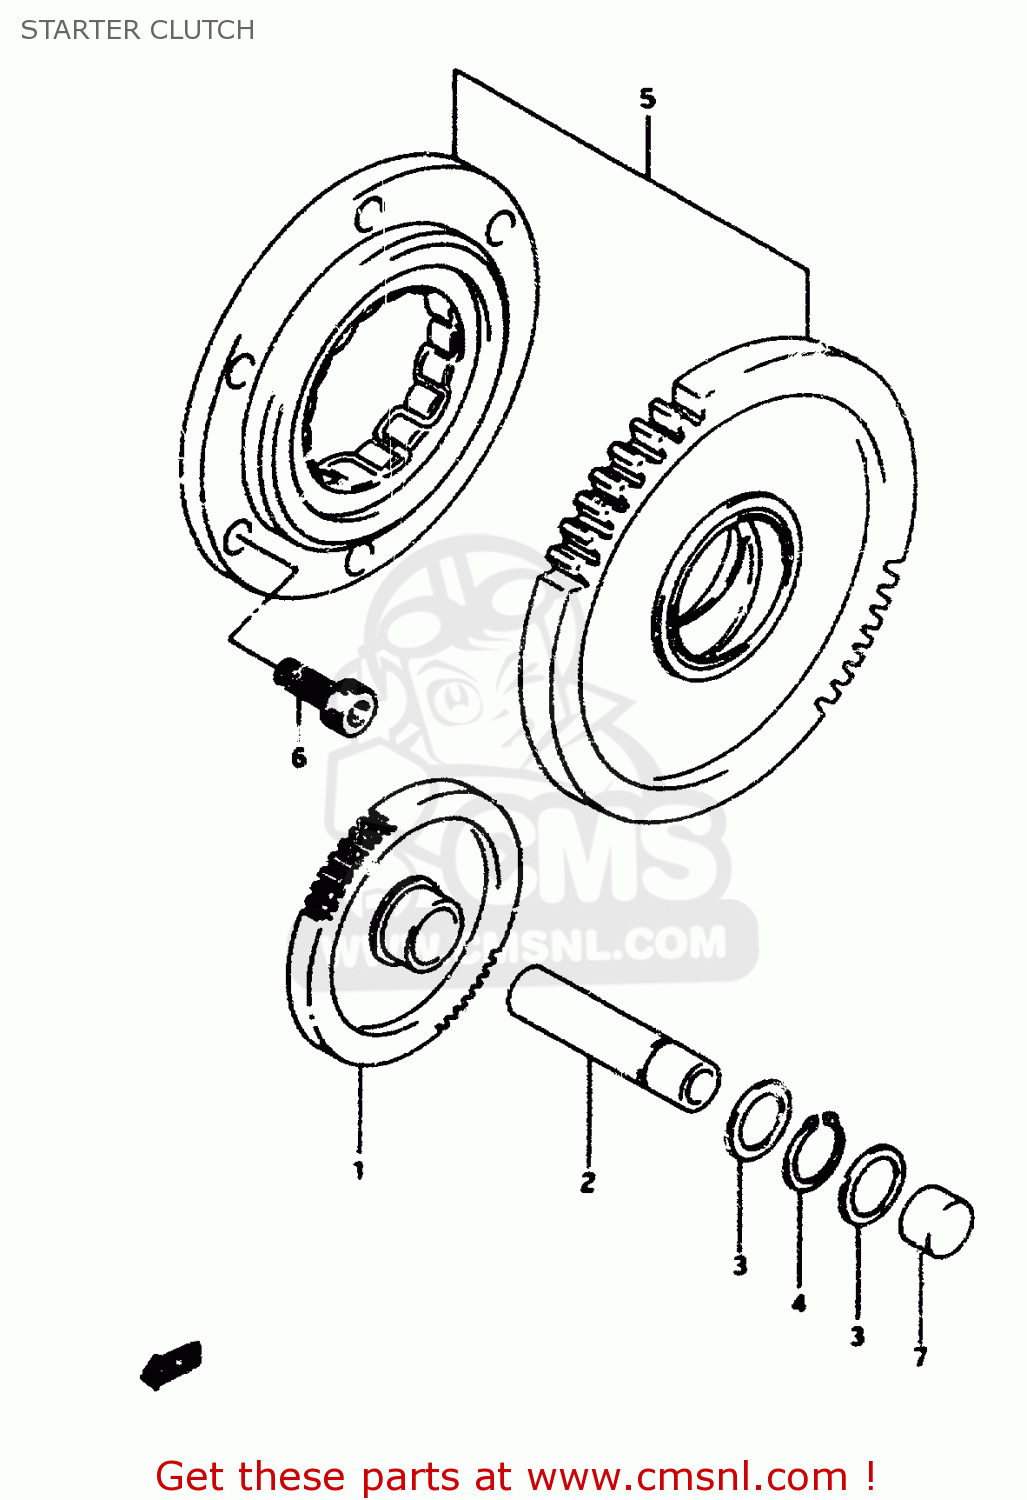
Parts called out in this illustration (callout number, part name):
1	GEAR,STARTER IDLE (NT:1
2	SHAFT,STARTER IDLE GEAR
3	WASHER
4	CIRCLIP,12 MM
5	CLUTCH SET,STARTER
6	BOLT
7	PLUG
